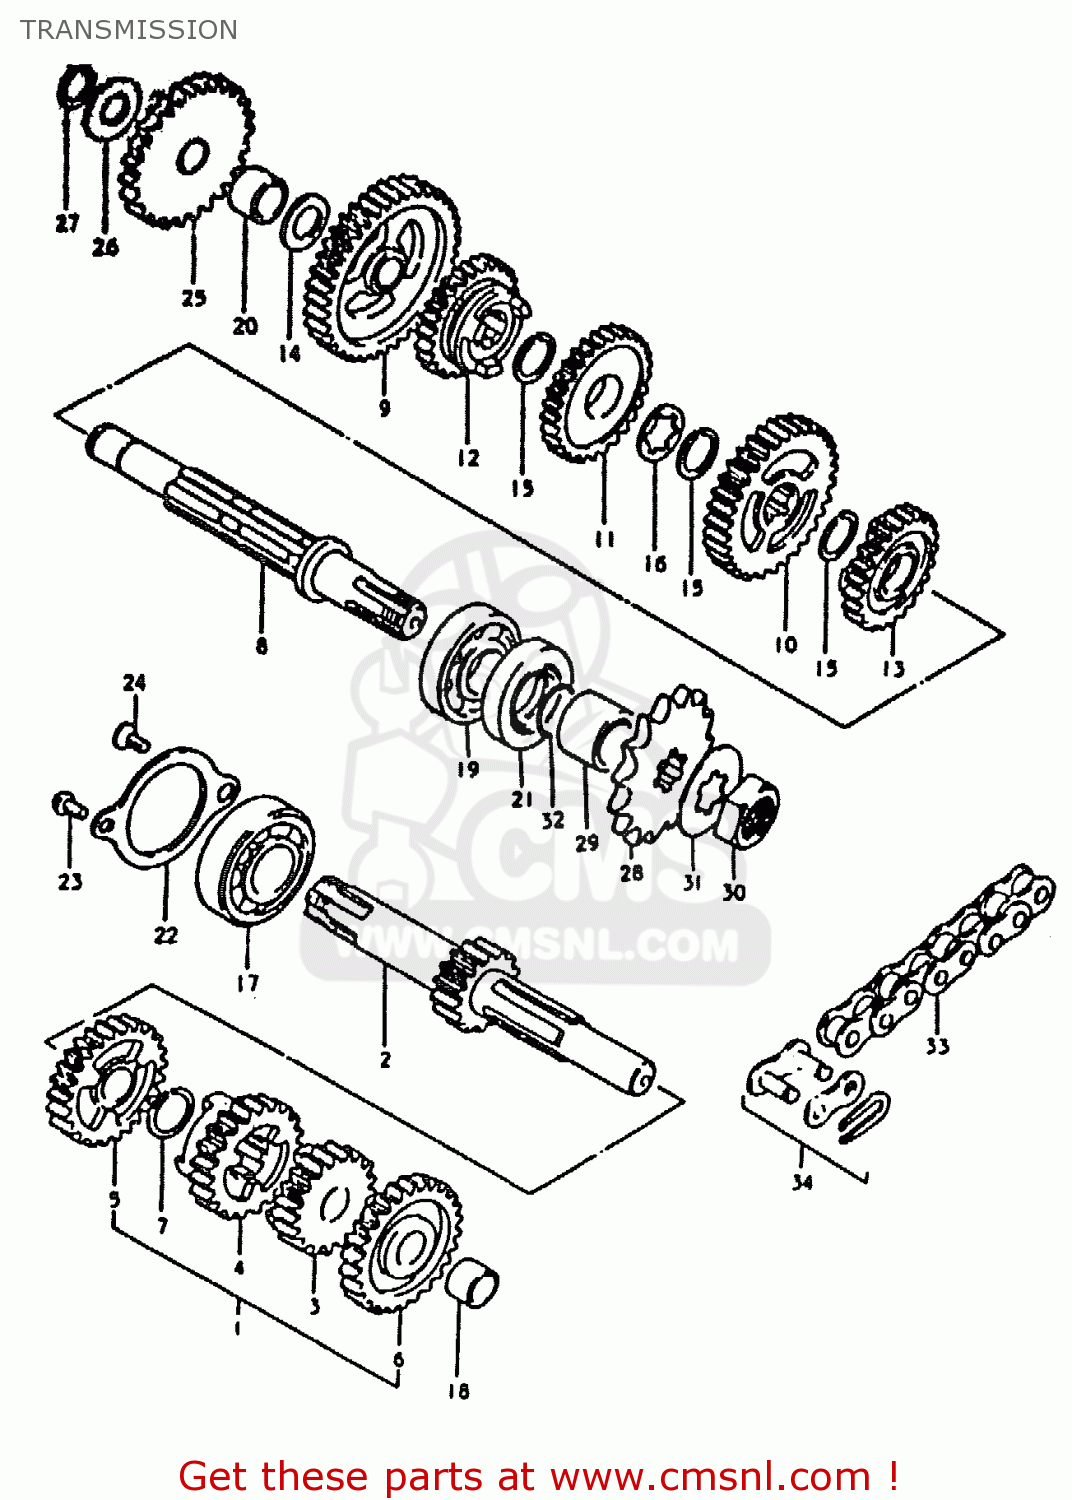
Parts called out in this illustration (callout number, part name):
1	SHAFT,COUNTER
2	SHAFT,COUNTER(NT:12)
3	GEAR,SECOND DRIVE
4	GEAR,THIRD DRIVE
5	GEAR,4TH DRIVE(NT:24)
6	GEAR,FIFTH DRIVE
7	CIRCLIP
8	SHAFT,DRIVE
9	GEAR,FIRST DRIVEN
10	GEAR,2ND DRIVEN(NT:33)
11	GEAR,3RD DRIVEN(NT:29)
12	GEAR,FOURTH DRIVEN
13	GEAR,5TH DRIVEN(NT:24)
14	WASHER(13X24X1)
15	CIRCLIP
16	WASHER,LOCK
17	BEARING
18	BUSH
19	BEARING
20	BUSH
21	SEAL,OIL(21X40X6)
22	RETAINER,CNTR SHAFT BEARING
23	SCREW
24	SCREW
25	GEAR,KICK STARTER IDLE
26	WASHER
27	CIRCLIP
28	SPROCKET,ENGINE(NT:12)
29	SPACER(17X21X13)
30	NUT
31	WASHER,LOCK
32	O RING(D:1,ID:16.8)
33	CHAIN ASSEMBLY,DRIVE
34	JOINT ASSEMBLY,CHAIN
